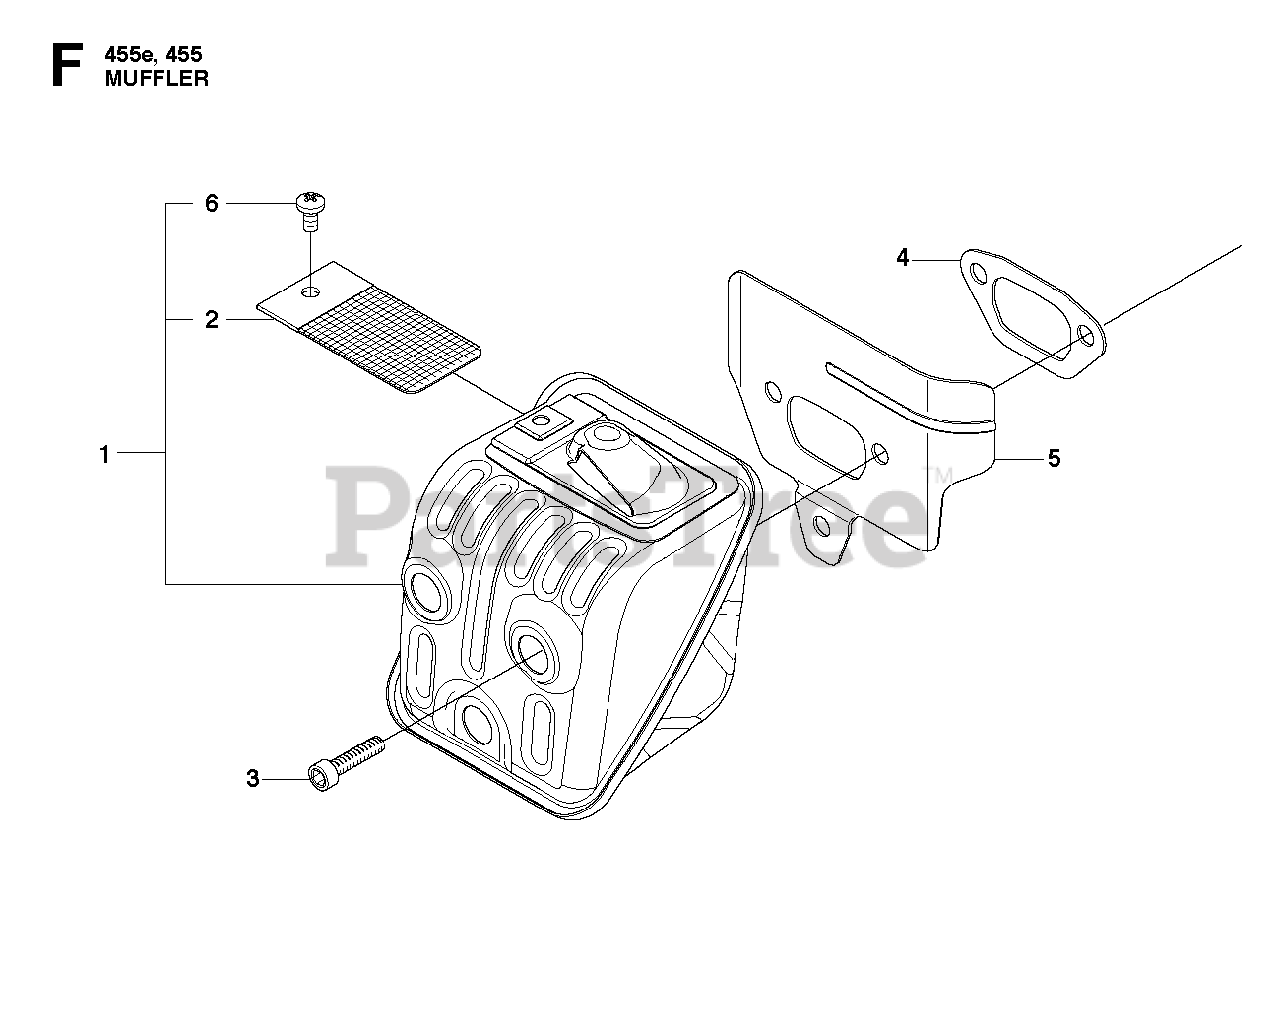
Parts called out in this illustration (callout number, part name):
1	MUFFLER ASSY
2	SPARK ARRESTOR SCREEN
3	SCREW MC6S 6X16
5	HEAT SHIELD
6	SCREW
